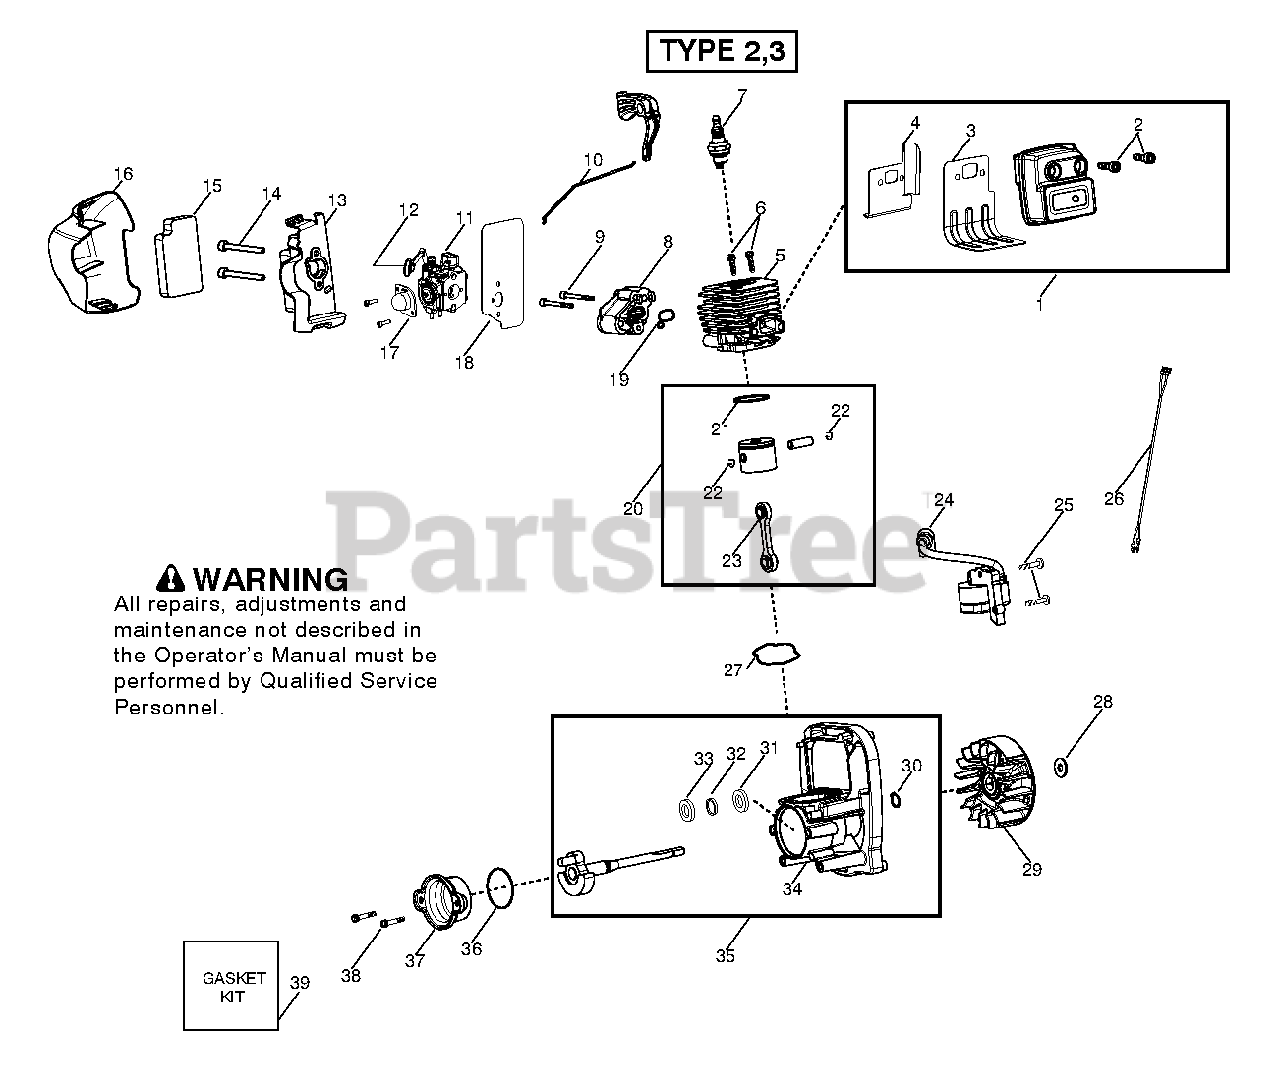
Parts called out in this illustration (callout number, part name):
1	ASSY MUFFLER WELDED
3	KIT GASKET 25CC
4	SHIELD MUFFLER HEAT
5	CYLINDER CHROME 25CC
7	PLUG-SPARK (RCJ-6Y)
8	ADAPTER CARBURETOR
10	LINKAGE THROTTLE
11	Carburetor Kit, C1U-W43
12	Choke Lever, C1U-W43
13	BASE AIRBOX PP GOLD
15	Air Filter, Foam
16	Air Box Cover, Black
17	PURGE BULB ZAMA
18	KIT GASKET 25CC
19	KIT GASKET 25CC
20	KIT PISTON CONN ROD
21	RING-PISTON
22	WRIST PIN RET.
23	KIT PISTON CONN ROD FORGED
24	KIT MODULE W/0 INTERRUPT
27	KIT GASKET 25CC
29	ASSY FLYWHEEL
30	RETAINING RING
31	OUTER BEARING
33	BEARING
34	CRANKCASE
35	ASSY CRANKCASE & CRANKSHAFT
36	KIT GASKET 25CC
37	ASSY REAR PLUG
39	KIT GASKET 25CC
